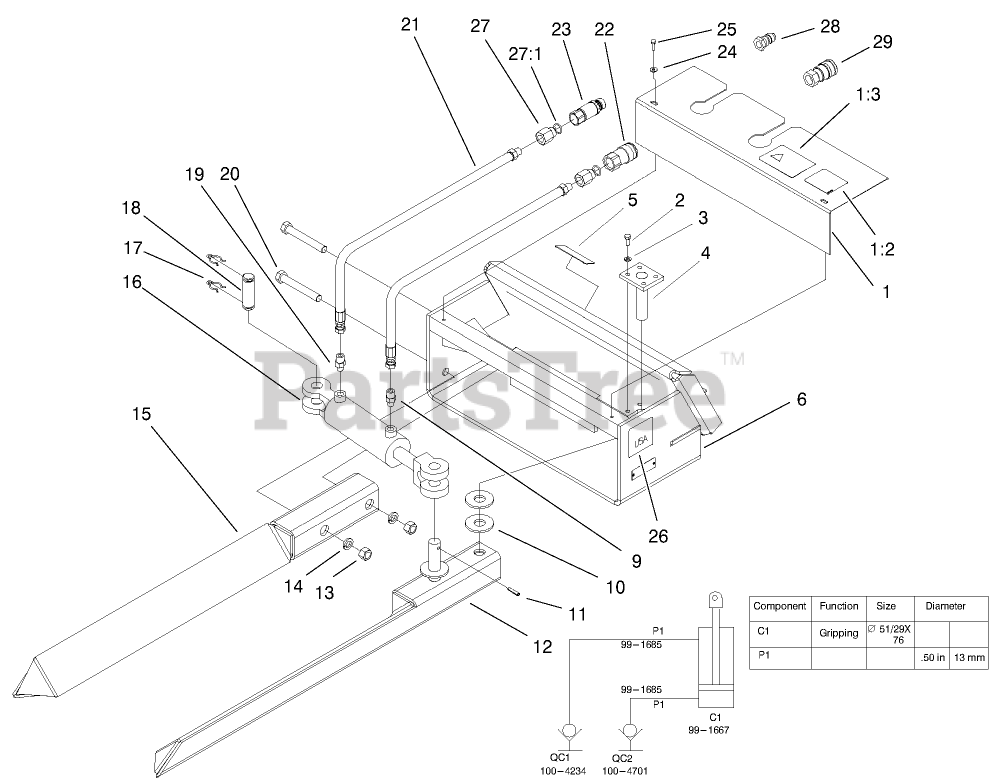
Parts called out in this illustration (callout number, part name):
1	SHIELD ASM
1:2	DECAL-WARNING
1:3	DECAL-RATING, LOAD
2	SCREW-HSH
3	WASHER-LOCK
5	DECAL-ATTACHMENT, DINGO
6	FRAME
9	CONNECTOR - STRAIGHT
10	WASHER-FLAT
11	PIN-ROLL, SLOTTED
12	ARM-PIVOT, LH
13	NUT-HEX
14	WASHER-LOCK
15	ARM-PIVOT, RH
16	CYLINDER - TREE FORK
16:1	KIT-SEAL
17	CLIP - PIN
18	PIN - CYLINDER PIVOT
19	CONNECTOR-STRAIGHT ORIFICE
20	SCREW-HH
21	HYDRAULIC HOSE ASM
22	COUPLER-FACE, FLUSH
23	NIPPLE-CONNECT, PRESSURE
24	WASHER-FLAT
25	SCREW-HSH
26	DECAL
27	ADAPTER-HYD
27:1	O-RING
28	DISCONNECT-QUICK, MALE
29	DISCONNECT-QUICK, FEMALE
